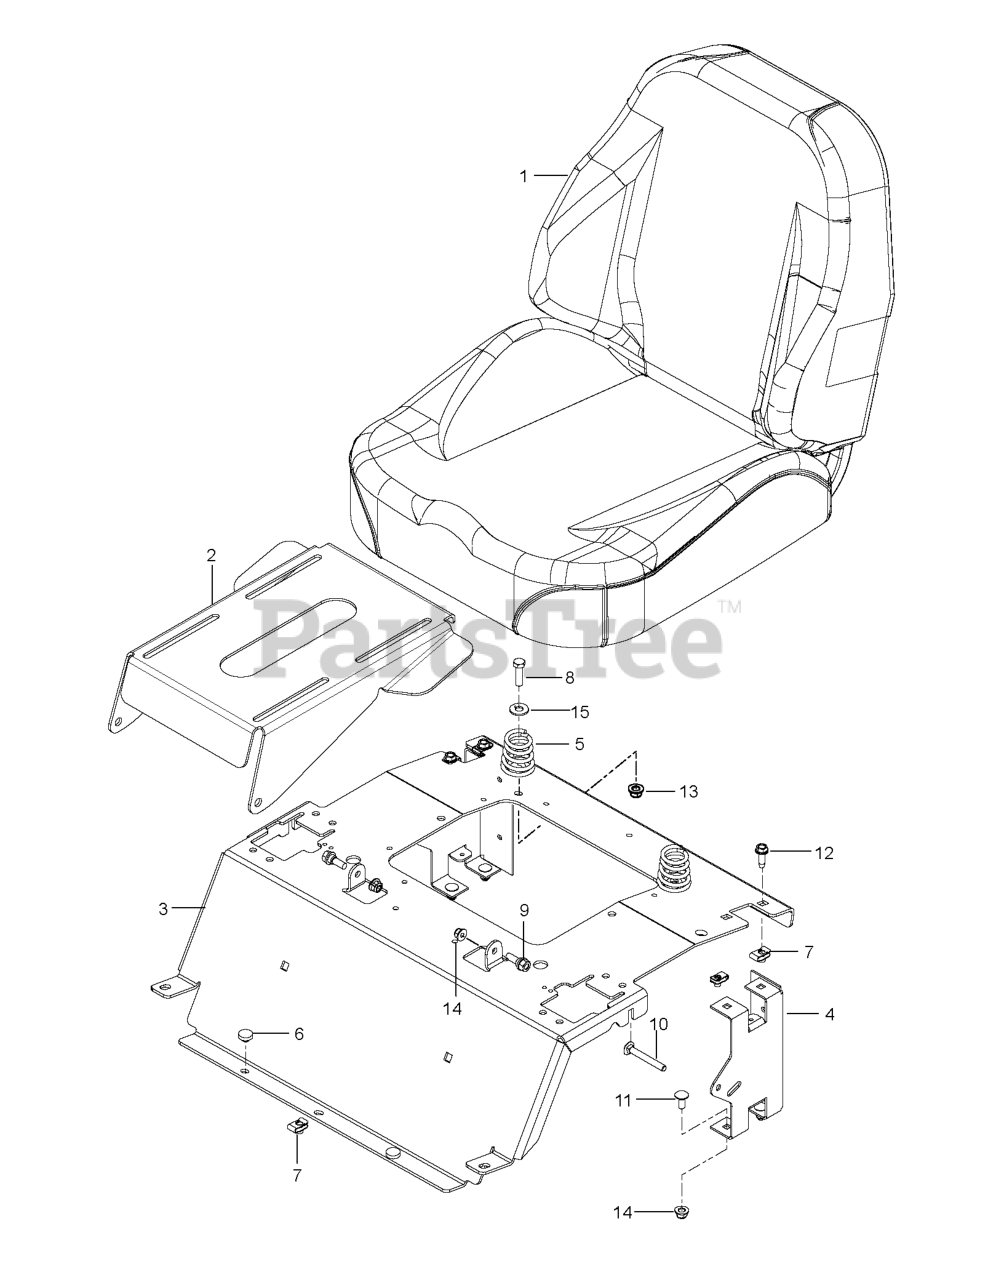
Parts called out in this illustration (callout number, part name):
1	SEAT.WOOD.BOTTOM.4-BOLT.REDMAX
2	PAN SEAT, 4-BOLT BLACK X428
3	PLATE SEAT SUPPORT; RZ SNAPPER
4	SUPPORT REAR SEAT BLACK
5	SPRING.COMPRESS.SEAT.TAPERED
6	GROMMET, BUMPER
7	U-CLIP 5/16-18 NUT RETAINER
8	BOLT
9	BOLT SHOULDER 5/16-18 UNC
10	RHSNB 5/16-18 X 2-1/2 GR5 ZD
11	BOLT 5/16C X 3/4" CARRIAGE
12	SCREW
13	NUT 3/8-16 HEX FLG NYLOC ZD
14	5/16-18 NYLOC FLANGE NUT
15	WASHER 3/8 FLAT
